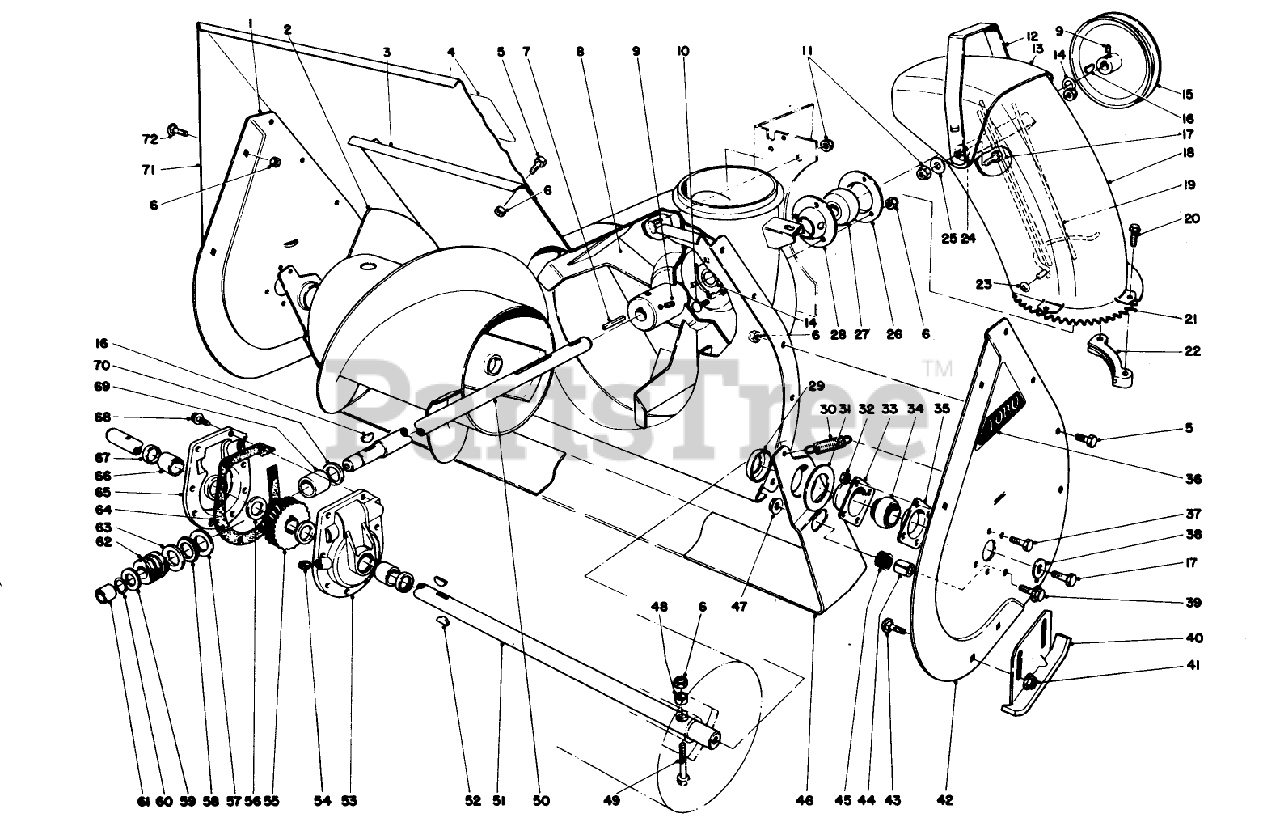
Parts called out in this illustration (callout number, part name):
1	Sideplate Auger Right
2	Auger Right
3	Auger Housing
4	Decal
5	SCREW-HH
6	NUT-LOCK, NI
8	IMPELLER WA RO
9	Set Screw
10	BOLT-CARR
11	NUT-LOCK, CONE
12	DEFLECTOR HANDLE B
13	Chute Deflector
14	WASHER
15	IMPELLER PULLEY
16	KEY-WOODRUFF
17	SCREW-HH
18	Chute
19	CHUTE GUARD WA 24
20	SPECIAL SCREW
21	Chute Swivel Gear
22	CHUTE RETAINER
23	NUT-PUSH
24	Rubber Washer
25	WASHER-BELLEVILLE
26	FLANGE-CUP, BEARING
27	Ball Bearing
28	FLANGE-CUP, BEARING
29	Positioner-Scraper
30	SPRING-TENSION
31	SCRAPER BLADE SPACER
32	NUT-LOCK, CONE
33	BEARING-FLANGE, FRONT
34	BEARING
35	BEARING-FLANGE, REAR
36	AUGER SIDE PLT DECAL
37	SCREW-HH
38	WASHER
39	SCREW-HHF
40	AUGER SKID WA R
41	NUT-HHF, WHIZ
42	Sideplate Auger Left
43	SCREW-CARR
44	SCRAPER STOP SPACER
45	SCRAPER STOP CUSHION
46	24 SCRAPER BLD
47	NUT-HF
48	SPACER-HUB, AUGER
49	Auger Bolt
50	Shaft Impeller
51	24 AUGER SHAFT
52	Key Woodruff
53	Gear Case (Incl. Ref. #66 & 77)
54	PLUG-PIPE, SQH
55	GEAR-WORM, 27T
56	WASHER-THRUST
57	WASHER-THRUST
58	BEARING-THRUST
59	WASHER-THRUST
60	Ring-Snap
61	BUSHING
63	THRUST-WASHER
64	asket
65	Gear Case (Incl. Ref. #66 & 67)
66	BUSHING
67	SEAL-OIL
68	SCREW-TAPTITE
69	BUSHING-SPECIAL
70	RING-QUAD
71	AUGER EXT 24 SCND R
72	SCREW-CARR
